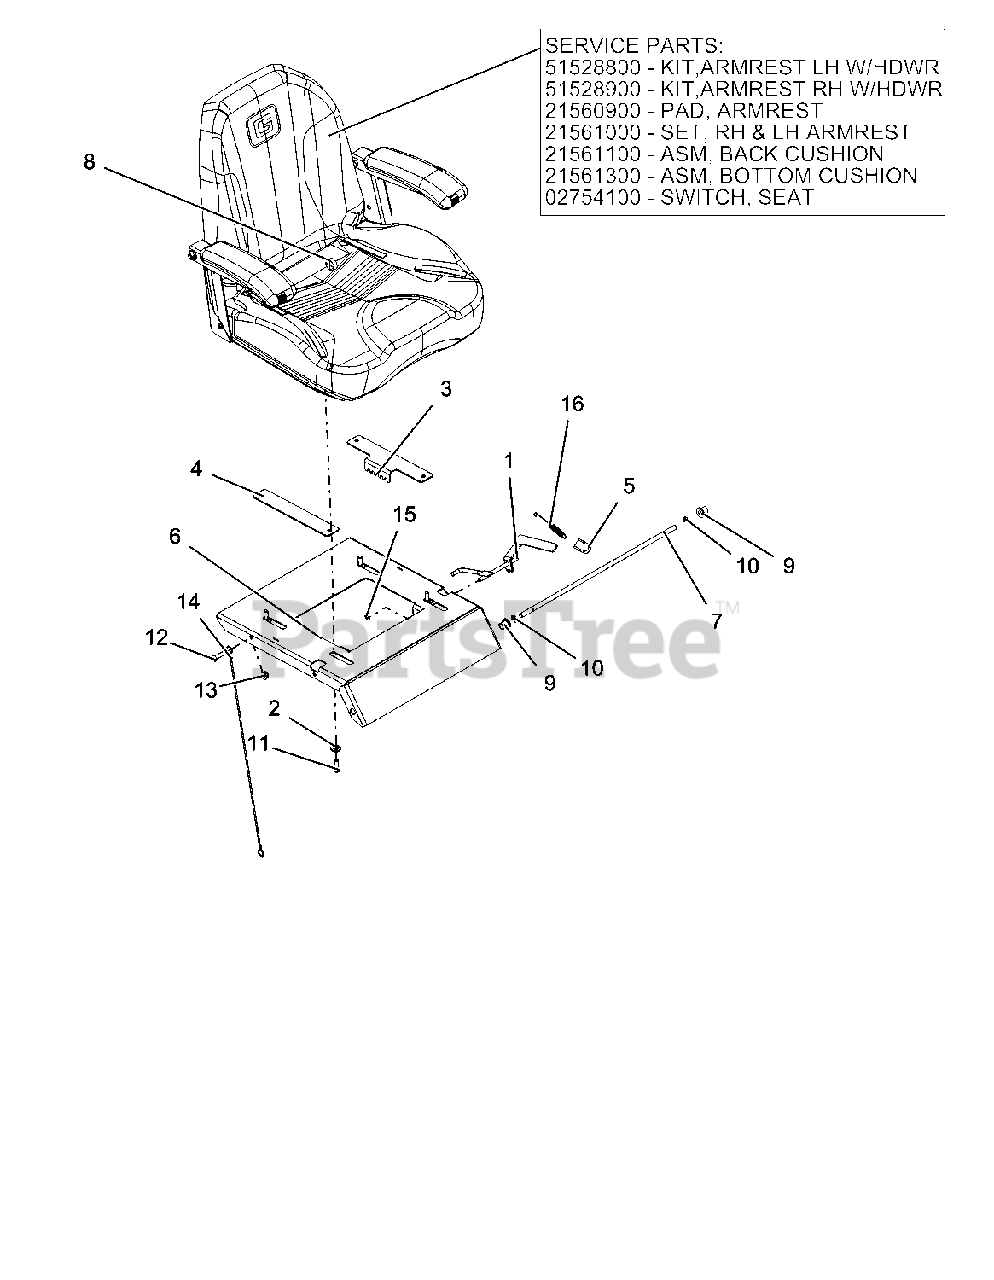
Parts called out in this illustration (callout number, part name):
1	WLDMT, ADJUSTABLE SEAT LATCH
2	BSHG, FLG .325X.499X.26X.88
3	PLATE, ADJUSTABLE SEAT TRACK
4	PLATE, ADJUSTABLE SEAT SLIDE
5	GRIP, SEAT LEVER, GREY
6	PLATE, SEAT
7	ROD, SEAT PIVOT
8	SEAT, MOWER ZT X
8	KIT, ARMREST LH W/HDWR
8	KIT, ARMREST RH W/HDWR
8	PAD, ARMREST
8	SET, RH & LH ARMREST
8	ASM, BACK CUSHION
8	ASM, BOTTOM CUSHION
8	SWITCH, SEAT
9	BSHG, FLANGE .380 X .580 X .667 X .875
10	RING, RETAINING-E .375X.035
11	SCR-SKH .31-18X1.00 BTNHD YWZC
12	BLT-HEX .31-18X1.00 GR5 YWZC
13	NUT-LK-NYL-FLG .31-18 YWZC
14	CABLE, WIRE (LANYARD)-.093X19.5
15	NUT, PUSH .312
16	SPRG, EXTENSION
